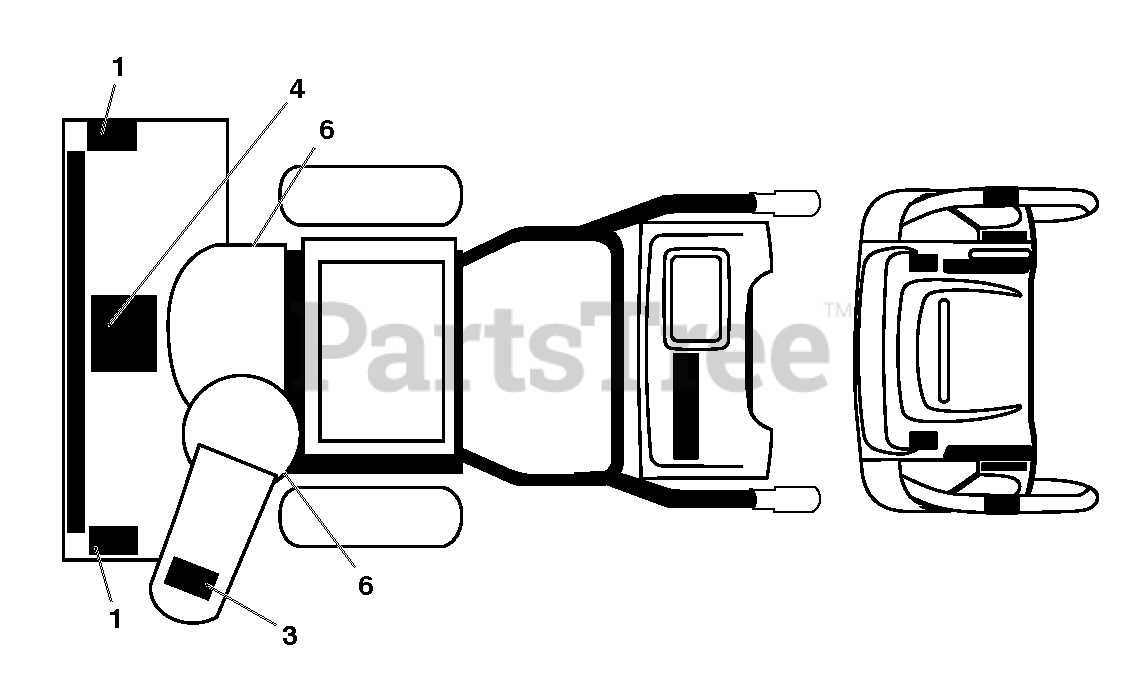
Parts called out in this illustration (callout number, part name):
1	DECAL.AUGER.SAFETY.
3	DECAL.CHUTE.SAFETY.
4	DECAL.AUGER."
6	DECAL.BELT.GUARD.
